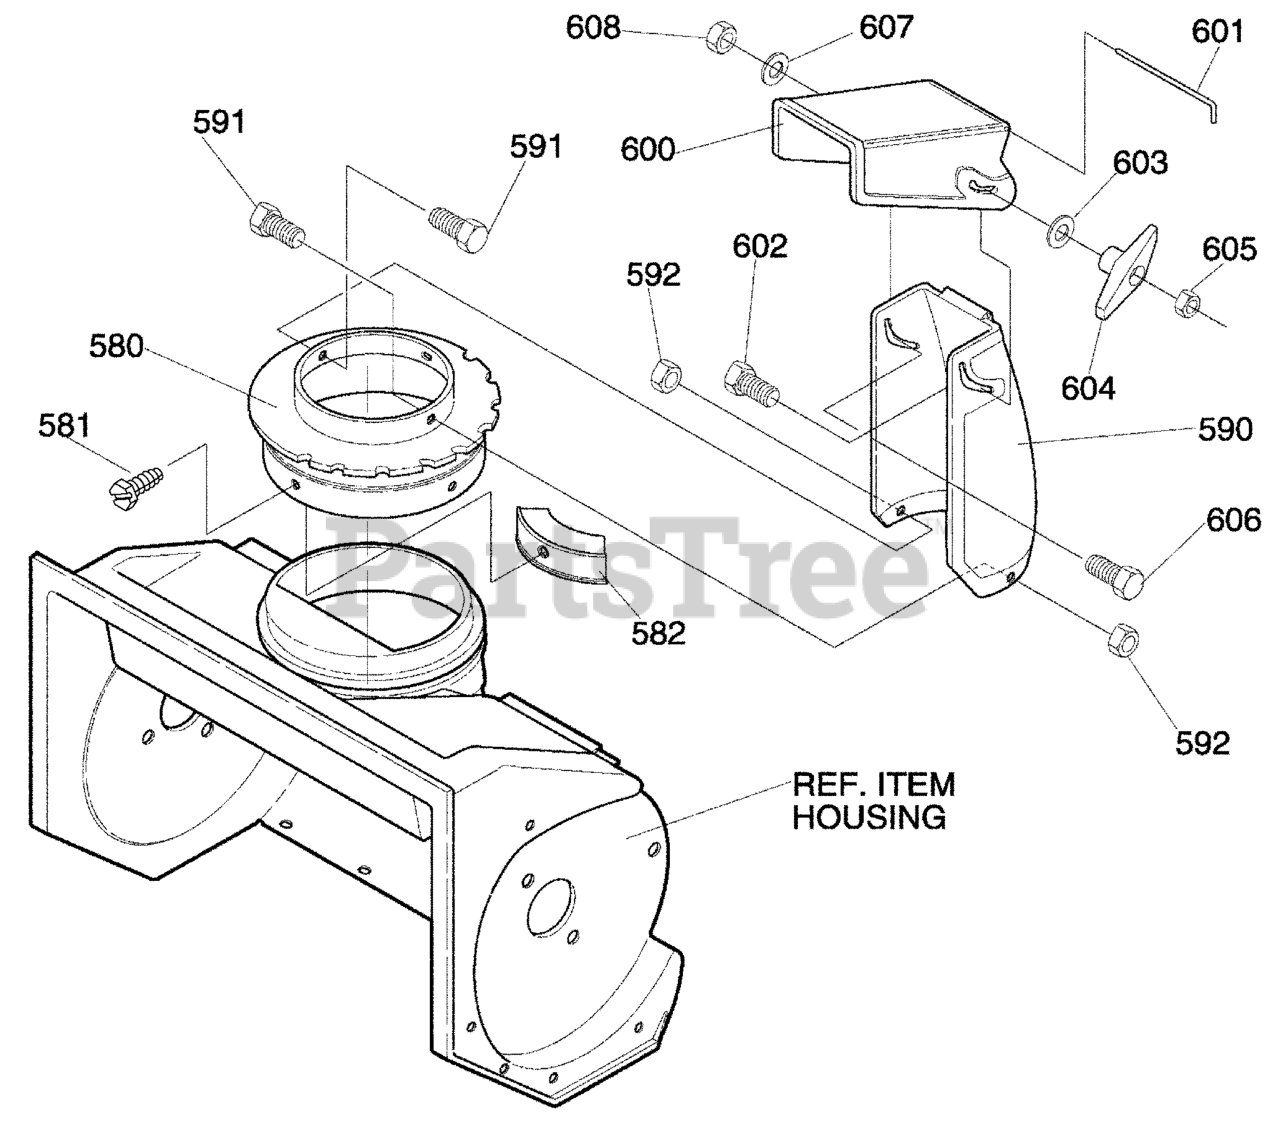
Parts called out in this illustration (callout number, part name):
580	RING, CHUTE
581	SCREW, #10X.50
582	GUIDE, CHUTE
590	CHUTE, LOWER
591	SCREW 1/4-20X.50
592	NUT, CNTRLK 1/4-2 YZ
600	CHUTE, UPPER
601	WIRE, HINGE
602	BOLT, CARRIAGE 5/16-18X1.25
603	WASHER, FLAT .349X.69X.066
604	KNOB, T
605	NUT, HEX 5/16-18
606	SCREW, 5/16-18 x 0.75
607	WASHER, FLAT .349X.69X.066
608	NUT, HEX 5/16-18
